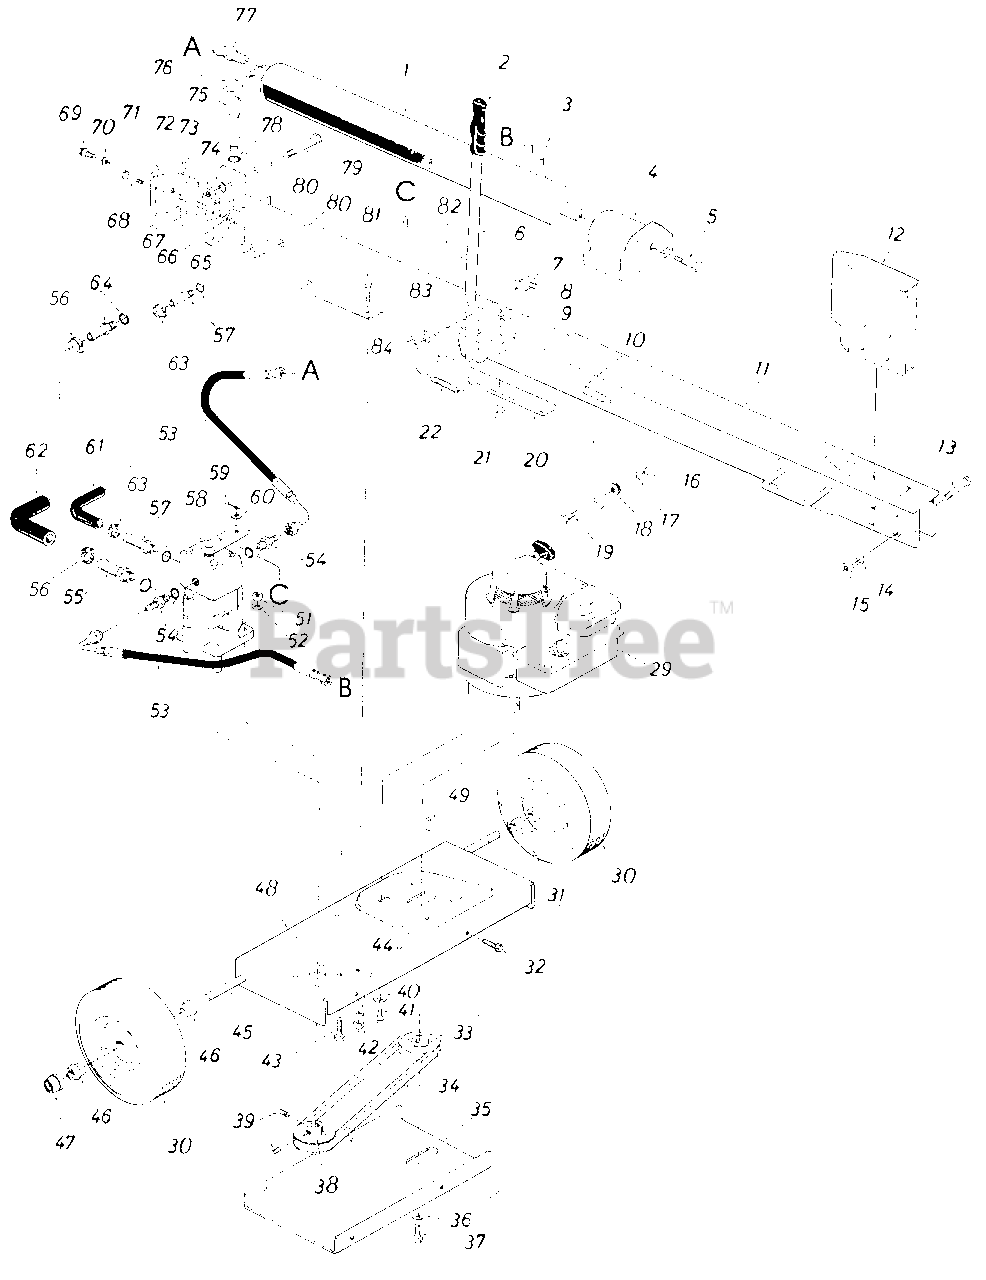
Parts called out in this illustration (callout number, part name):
1	2-1/2" Cylinder Ass'y. Comp.
2	Grip
3	90 Elbow Adapter
4	Pusher Plate
5	Shoulder Bolt 5/8" Dia. x .660" Lg. 1/2-13 Thd.
6	Engagement Handle
7	Adjustment Ferrule
8	Hex Nut 5/16-18 Thd.*
9	L.Wash. 5/16" I.D.*
10	Strainer Tube Ass'y.
11	Oil Tank Ass'y. Comp
12	Wedge Ass y.
13	Hex Bolt 5/8-18 x 3.50" Lg. ( G rade 5)
14	L.Wash. 5/8" I.D.
15	Hex Nut 5/8-18 Thd.*
16	Hex Nut 3/8-16 Thd.*
17	L.Wash. 3/8" I.D.*
18	Rubber Wash.
19	Shoulder Bolt .498x .340
20	Engagement Brkt.
21	Shoulder Bolt .437" Dia. x .180" Lg.
22	Extension Spring .50" O.D. x 4.25" Lg.
29	Engine - B&S
30	Wheel Ass'y. Comp. 10.0" x 2.75
31	Sleeve .632 " I.D. x .875" O.D. x .90" Lg.
32	Hex Wash. Hd. Self Tap. Scr. 1/4-20 x . 50" Lg.
33	1/2" V-Pulley 7/8" I.D. x 7/8" I.D. x 3-1/4" O.D.
34	"V"-Belt (4L) 1/2" V x 30" Lg.
35	Belt Cover
36	L.Wash. 5/16" I.D.*
37	Hex Bolt3/8-24 x 1.0" Lg.*
38	1/2 (4L) "V"-Pulley 5/8" I.D. x 3-1/2" O.D.
39	SetScr. 1/4-28x .25" Lg.
40	Bell.Wash..40" I.D. x .88" O.D.
41	Hex Wash. Hd. TT-Tap Scr. 3/8-16 x .87 " Lg.
42	Hex Nut 5/16-24Thd.*
43	Hex Bolt 5/16-18 x 1.00" Lg.*
44	L.Wash. 5/16" I.D."
45	Axle Shaft 518" Dia. x 25.5" Lg.
46	FlangeBrg.w/Flats.631" I.D.
47	Push Cap 5/8" Dia. Rod
48	Frame - Engine
49	Sq. Key 3/16" x 3/16" x 1.50" Lg.*
51	Hex Nut 5/16-18 Thd.*
52	L.Wash. 5/16" 1. D . *
53	H igh Pressure Hose
54	Adapter - or Boss to MJIC 9/16-18 to 7/16-20
55	Adapter 3/4" Tubing to 3/4 -16 M-Boss
56	Hose Clamp 5/8" I.D.
57	Adapter 1/2 " Tu be 9/16-18 or M-Boss
58	Valve Ass'y.
59	Cotter Pin 3/32" Dia. x .75" Lg.*
60	Fl.Wash. 344" I.D. x .62" O.D. x .063
61	Return Hose.50" I.D.
62	Suction Hose.75" I.D.
63	Hose Clamp 1/4" I.D.
64	Adapter 1.0" Tube 1-1/16- 12 "O"-Ring
65	Hex Nut 5/16-18 Thd.*
66	L.Wash . 5/16 " I . D . *
67	Fl.Wash. .343" I.D. x .687" O.D. x .062
68	Hex Bolt 5/16-18 x 1.50"
69	Hex Hd. Tap Scr. 5/16"
70	Gasket
71	End Plate
72	Gasket
73	Hex Nut 3/4" Thd.*
74	L.Wash. 3/4" I.D.*
75	Filler Tube Ass'y.
76	Oil Fill Cap
77	45ø Male Adapter 7/16-20 MJ-1/4-18 NP
78	"O"-Ring .92" I.D. x 1.16" O.D. x .116 Dia.
79	Hex Bolt 3/4" x 4.0" Lg.
80	Hex Nut 1 1/16-12 Thd.
81	Hex Bolt5/16-24x 1.00" Lg.(Grade 5)
82	Engagement Rod 16.75" Lg.
83	Fl.Wash. .344" I.D. x.62" O.D. x .063
84	Hair Pin Cotter 5/16" Dia.
